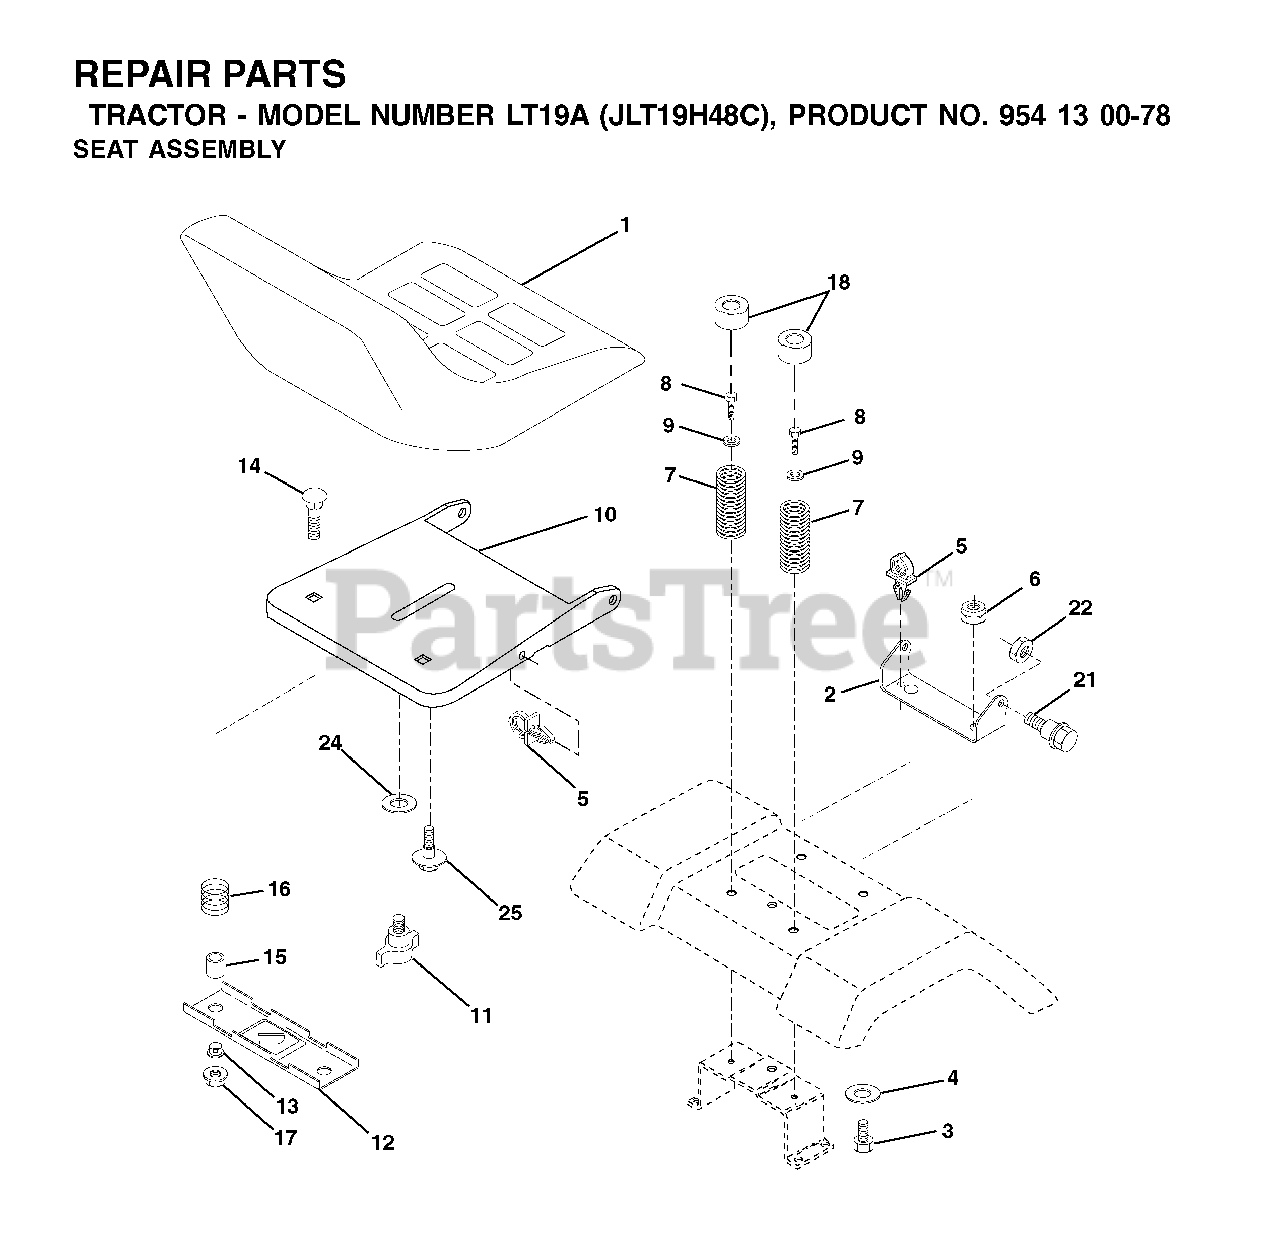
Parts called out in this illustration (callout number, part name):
2	SEAT PIVOT BRKT
4	WASHER PM
5	PUSH CLIP
6	NUT
7	SPRING COMPRESSION
8	SCREW 3/8-16X1
9	WASHER
10	PAN SEAT
11	KNOB.SEAT.ADJ.WINGNUT
12	BRKT SWITCH
14	BOLT.ROUND.HEAD.SQUARE.NECK
15	SPACER SPLIT
16	SPRING COMPRESSED
17	NUT T
18	CAP SPRING
21	BOLT.SHOULDER.5/16-18
22	NUT.71038.31-18.HEX.NYLOCK
25	BOLT,SHOULD
